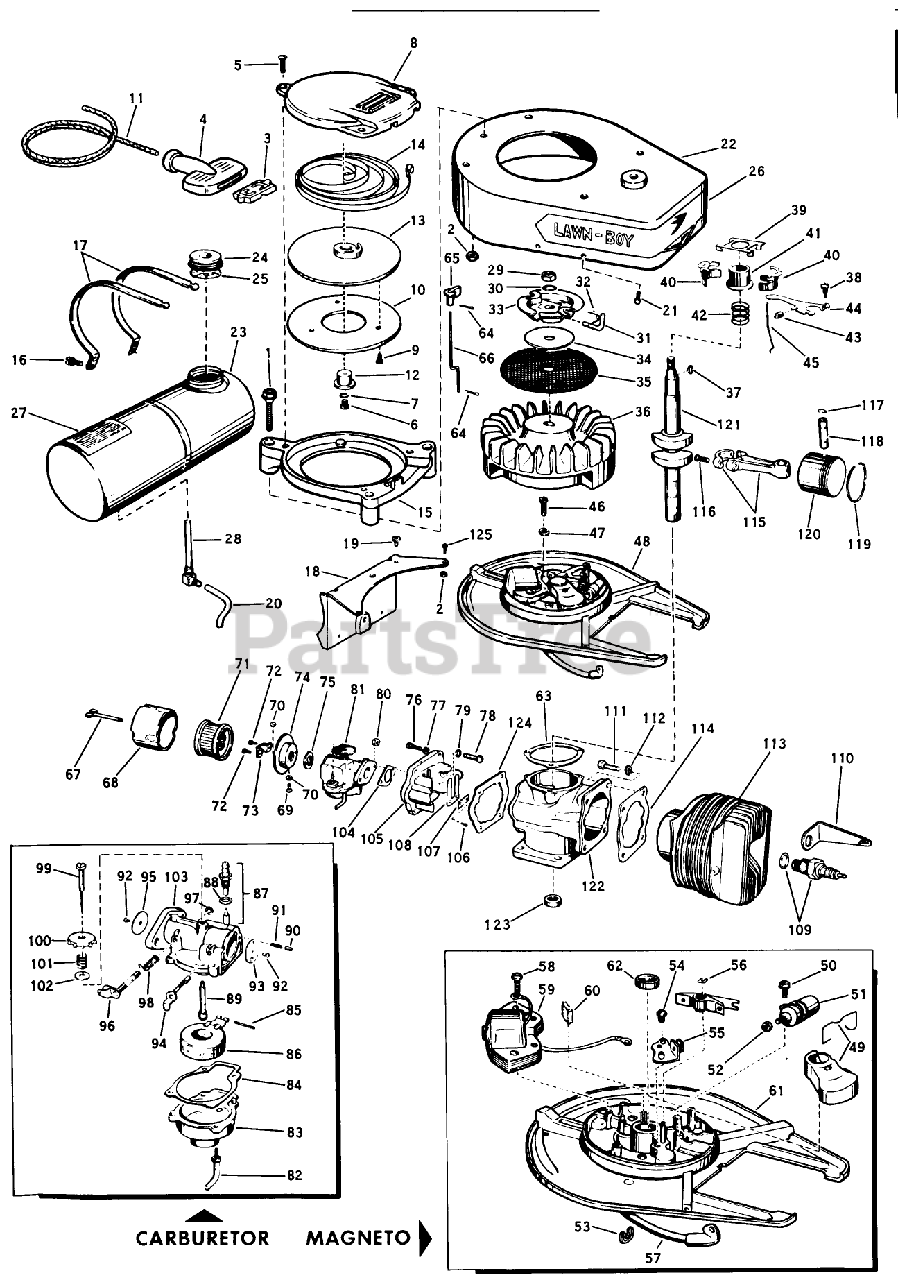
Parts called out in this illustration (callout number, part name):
10	Plate-Pulley
14	RECOIL SPRING
21	SCREW S
24	Gas Cap
27	Decal-Instruction
31	PIN - STARTER
41	COLLAR S
43	WEAR BLOCK S
44	GOVERNER LEVER AY
45	GOVERNOR ROD S
55	BREAKER AY. S
63	GASKET S
64	Cotter Pin-Choke Knob
65	KNOB, CHOKE BAR
76	SCREW S
80	STOP NUT
92	Screw-Choke Disc
98	SPRING
99	NEEDLE AY. S
101	Spring-Ndl. Adj.
104	GASKET S
107	PLATE-BACKUP, REED
109	Spark Plug
113	Cylinder Sleeve Assembly
116	Screw-Connecting Rod
119	Ring-Piston
121	Crankshaft
124	GASKET
